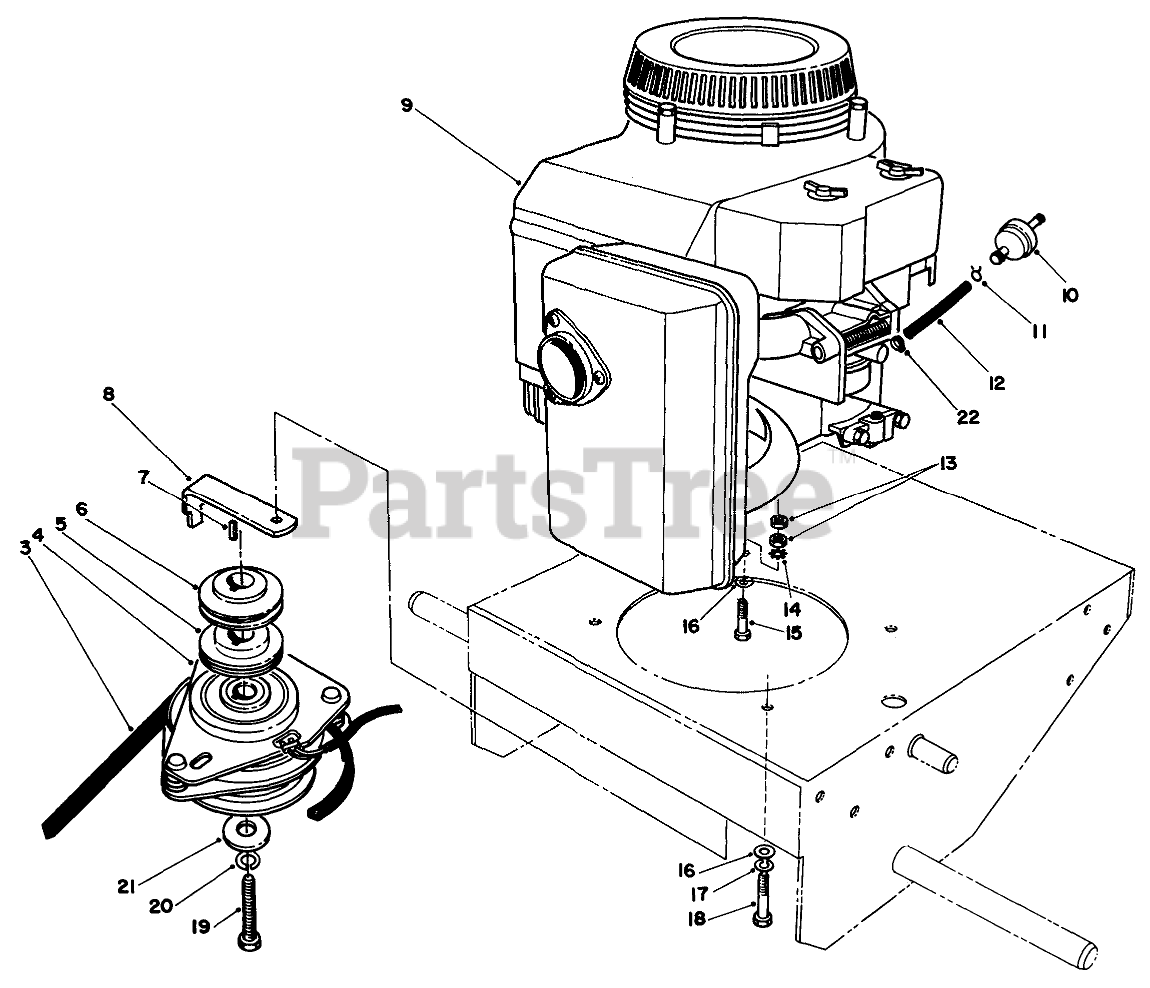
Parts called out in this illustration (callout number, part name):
3	V-BELT, DRIVE
4	CLUTCH/BRAKE
5	SHEAVE-LOWER HALF
6	SHEAVE-UPPER HALF
7	KEY-SQUARE
8	Retainer-Clutch
10	FILTER-FUEL
11	CLAMP-HOSE
12	HOSE-FUEL
13	NUT-JAM
14	WASHER-LOCK
15	SCREW (ENGINE, GROUND)
16	WASHER-PLAIN
17	WASHER-LOCK
18	SCREW-HH
19	SCREW-CLUTCH
20	WASHER-LOCK
21	WASHER-CLUTCH
22	CLAMP-WORM
